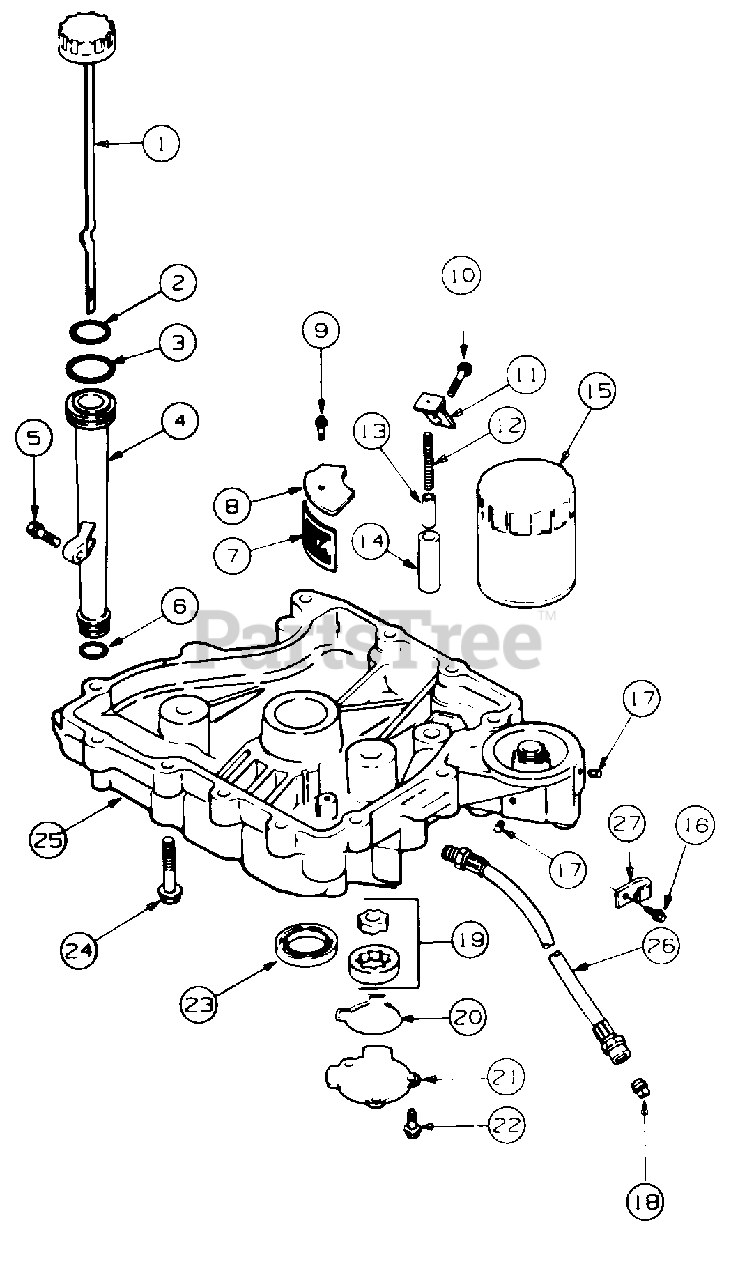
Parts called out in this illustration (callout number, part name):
1	Dipstick Assy
2	O-Ring, Dipstick
3	O-Ring, Upper Oil Fill Tube
4	Tube, Oil Fill
5	Screw, Oil Fill Tube, M5 X .08 X 20
6	O-Ring, Lower Oil Fill Tube
7	Screen, Oil Pickup
8	Cover, Oil Pickup Screen
9	Screw, Screen Cover
10	Screw, Oil Pump Relief Valve Bracket, M10 X 1.5 X 25
11	Bracket, Oil Pump Relief Valve
12	Spring, Oil Pump Relief Valve
13	Piston, Oil Pump Relief Valve
14	Body, Oil Pump Relief Valve
15	Filter, Oil
16	Screw, Hex Wash Hd Tapp, 5/16-18 X .50 Lg
17	Plug, Sq Hd Solid, 1/8 NPTF
18	Plug, Sq Hd Solid, 3/8 NPTF
19	Pump, Oil Assy
20	O-Ring, Oil Pump Cover
21	Cover, Oil Pump
22	Screw, Oil Pump Cover, M5 X 0.8 X 16
23	Seal, Oil
24	Screw, Oil Pan, M8 X 1.25 X 45
26	Hose, Oil Drain
27	Clip, Drain Hose
